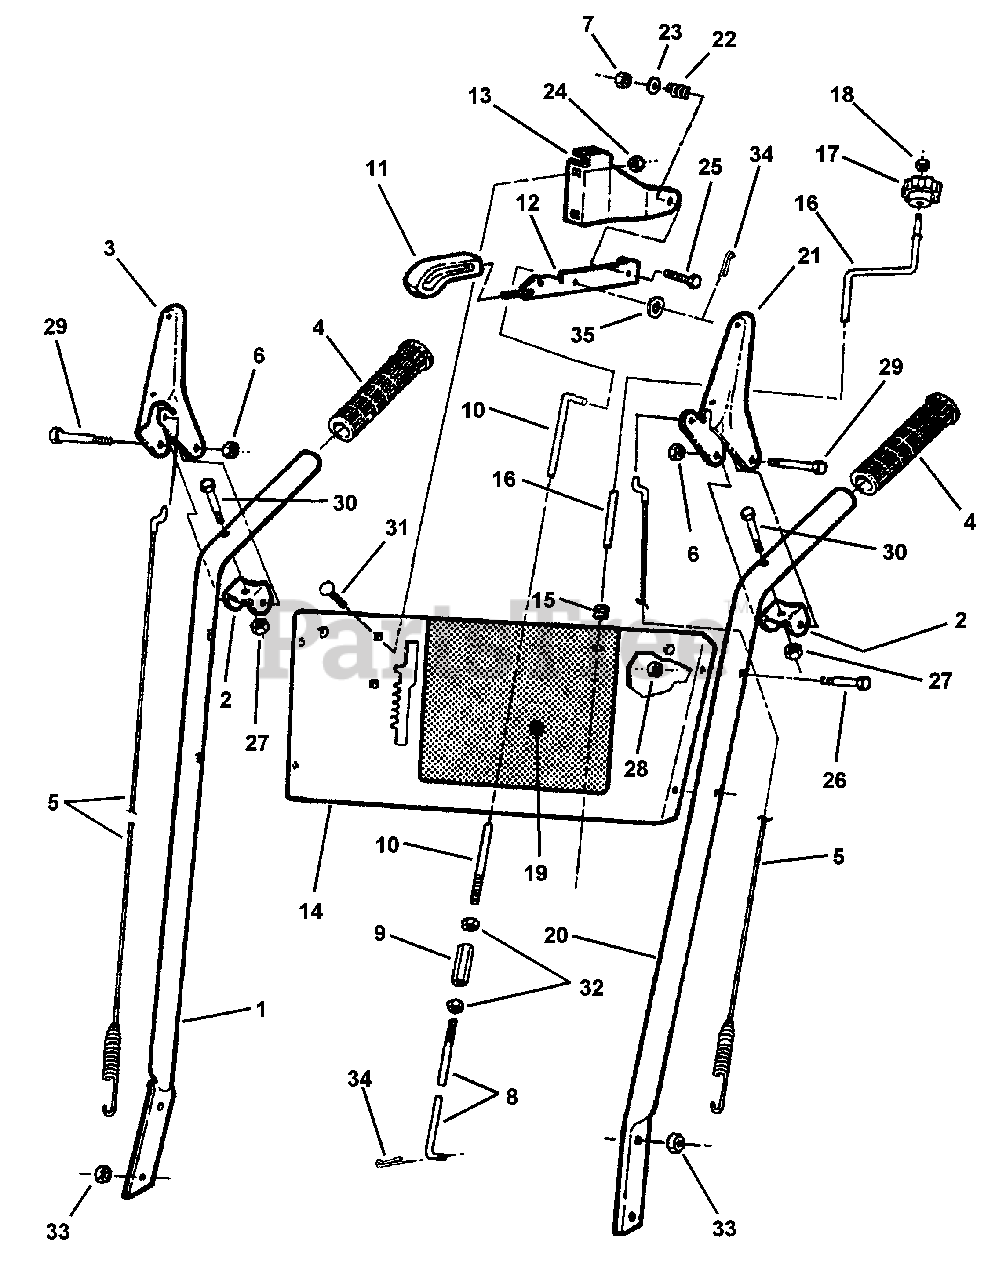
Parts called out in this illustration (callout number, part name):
1	BAR, Right Side Handle
2	BRACKET, Handle
3	HANDLE, Right Side
4	GRIP, Handle
5	CABLE, Clutch
6	NUT, 1/4 Push
7	NUT, 5/16-24 Hex Center Lock, Grade B
8	ROD, Lower Shift
9	CONNECTOR
10	ROD, Upper Shift
11	KNOB, Shift Handle
12	HANDLE, Shift
13	BRACKET, Shift Lever
14	PANEL, Control
15	BUSHING
16	CRANK, Chute
17	KNOB, Chute Crank
18	NUT, 5/16-18 Hex Center Lock, Grade B
19	DECAL, Control-8/24
20	BAR, Left Side Handle
21	HANDLE, Left Side
22	SPRING, Shift Lever
23	WASHER, 5/16 Flat
24	NUT, 1/4-20 Hex Flange Lock
25	SCREW, 5/16-24 x 1-3/4" Hex Head Cap, Grade 2
26	SCREW, 5/16-18 x 1-1/2" Hex Head Cap, Grade 5
27	NUT, 1/4-28 Hex Top Lock
28	NUT, 5/16-18 Hex Center Lock, Grade B
29	PIN, 1/4 x 1-7/8" Clevis
30	SCREW, 1/4-28 x 1-3/8" Hex Head Cap, Grade 5
31	BOLT, 1/4-20 x 1/2" Short Neck Carriage, Grade 5
32	NUT, 3/8-16 Hex, Grade B
33	NUT, 5/16-18 Hex Flange Lock, Grade 5
34	PIN, 1/8 x 1" Cotter
35	WASHER, 3/8" Flat
